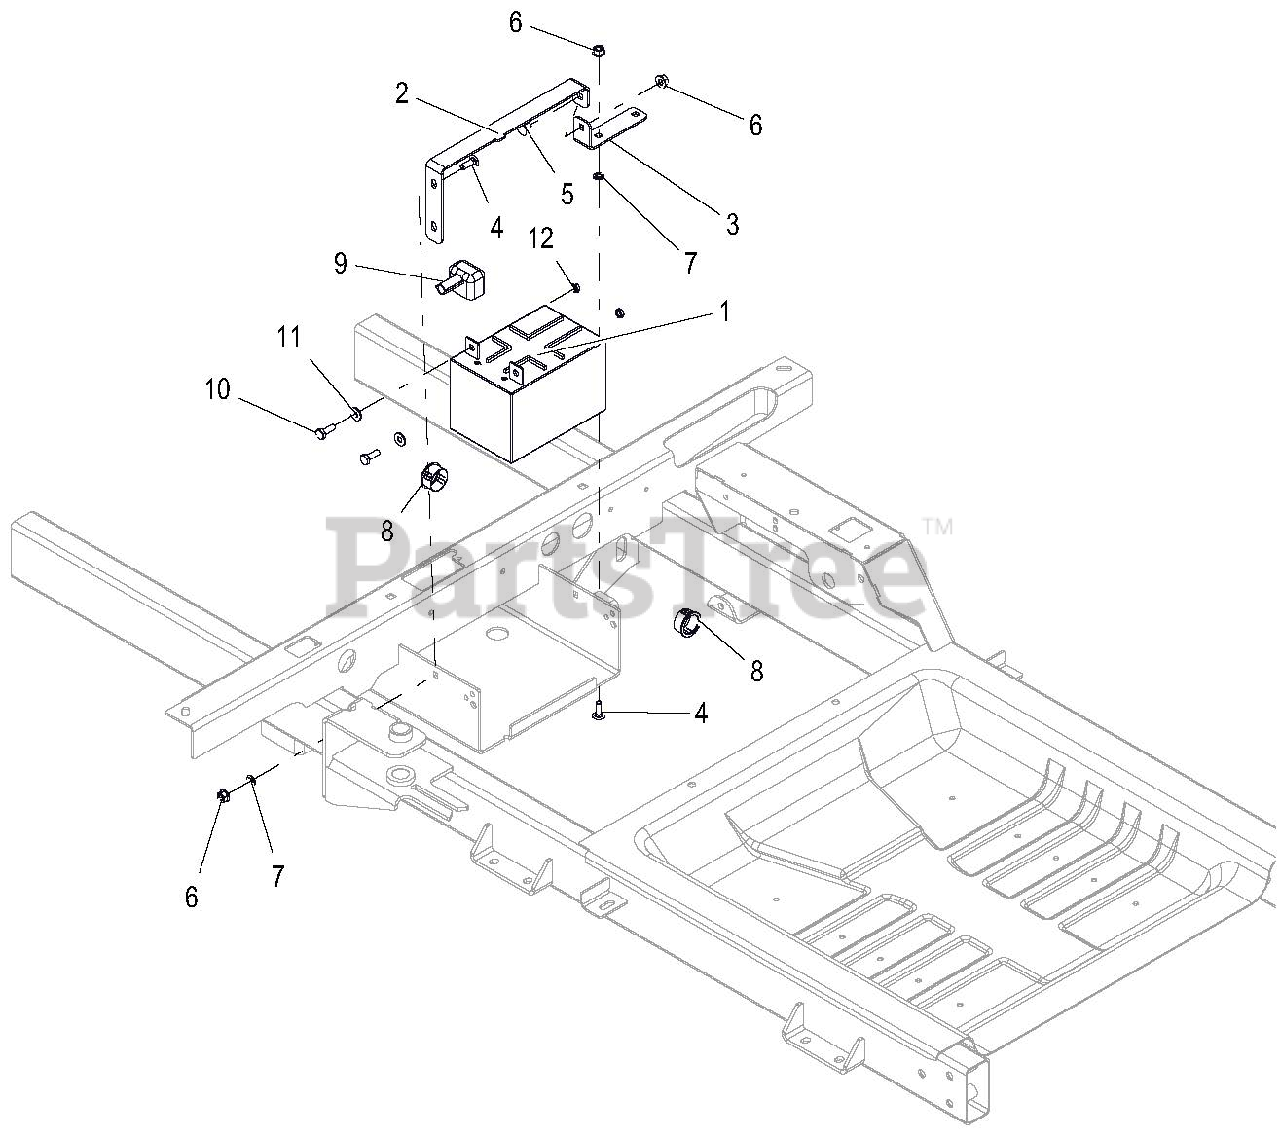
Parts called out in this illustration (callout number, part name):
1	BATTERY, 12V 12A -190CCA
2	BRKT, BATTERY HOLD-DOWN
3	BRKT, BATTERY
4	BLT-RDHDSQNK .25-20X.75 G5 YWZC
5	BLT-RDHDSQNK .25-20X.50 G5 Y
6	NUT, LK-TOP-FLG .25-20 YWZC
7	NUT, PUSH .25X.50 O.D.
8	BSHG, PANEL SNAP .937X1.109X.56
9	INSULATOR
10	BLT-HEX .25-20X.75 GR5 YWZC
11	WSHR-FL-STL.281X.62X.065 YWZC
12	NUT-KEPS 10-24
